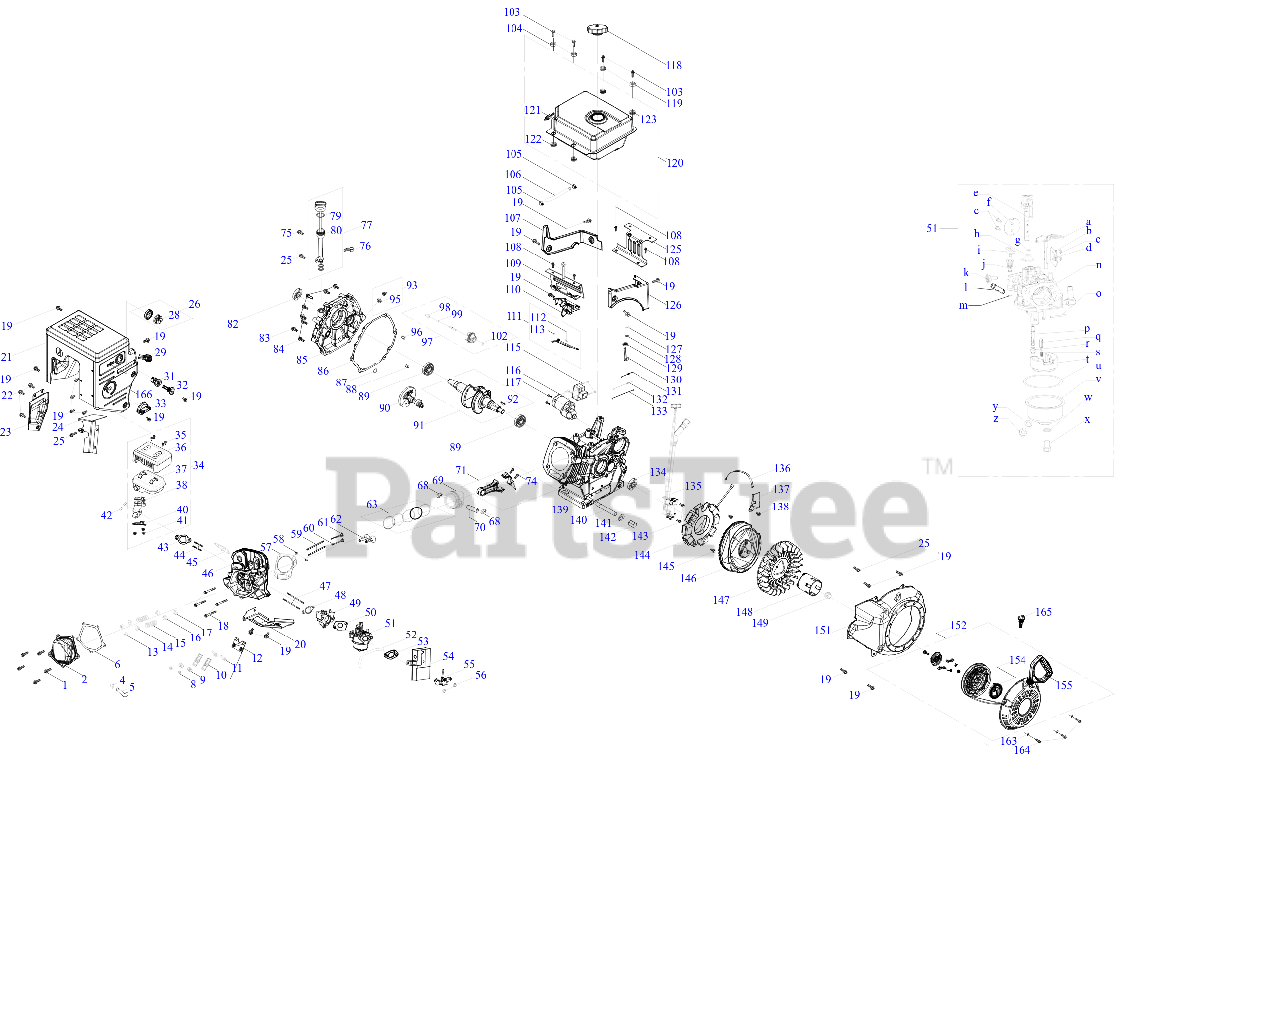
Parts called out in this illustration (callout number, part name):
1	BOLT M6-1 x 16 GR8.8
2	VALVE COVER
4	BREATHER HOSE CLAMP
5	BREATHER HOSE
6	VALVE COVER GASKET
8	PIVOT LOCKING NUT
9	VALVE ADJUST NUT
10	ROCKER ARM
11	ROCKER STUD BOLT
12	PUSH ROD GUIDE
13	EXHAUST VALVE ADJUSTER
14	EX VALVE SPRING RETAINER
15	VALVE SPRING
16	VALVE SPRING RETAINER
17	INTAKE VALVE SEAL
18	SCREW M4 x 55
19	BOLT M6-1 x 12 GR8.8
20	CYLINDER BAFFLE
21	MUFFLER SHIELD
22	BOLT M6-1 x 10 GR8.8
23	MUFFLER BAFFLE
24	CARBURETOR HEAT SHIELD
25	BOLT M6 x 16
28	PRIMER BULB
29	THROTTLE CONTROL KNOB
31	IGNITION SWITCH
32	IGNITION KEY
33	CHOKE KNOB
34	MUFFLER ASSEMBLY W/MNFLD
36	MUFFLER GUARD
37	MUFFLER BODY
38	EXHAUST MANIFOLD GASKET
40	NUT-RET EXHAUST BGBLK
41	HEX NUT M8 - 1.25
42	NUT M8-1.25
43	MUFFLER GASKET
44	STUDS M8-1.25 x 48.5
45	SPARK PLUG
46	CYLINDER HEAD
47	STUD M6-1 x 104
48	INTAKE GASKET
49	CARBURETOR INSULATOR
50	CARBURETOR GASKET
51	CARBURETOR ASSEMBLY
52	HOSE 3.2 x 6.5 x 240
53	AIR CLEANER GASKET
54	HEATE BOX
55	CHOKE ASSEMBLY
56	HEX NUT
57	CYLINDER HEAD GASKET
58	DOWEL PIN
59	PUSH ROD
60	INTAKE VALVE
61	EXHAUST VALVE
62	TAPPET
63	PISTON RING SET
68	PISTON PIN SNAP RING
69	PISTON
70	PISTON PIN
71	CONNECTING ROD ASSEMBLY
74	BOLT M8-1.25 x 38 GR10.9
75	BOLT M6-1 x 8 GR8.8
76	OIL TUBE SUPPORT BRACKET
77	DIPSTICK ASSEMBLY
79	DIPSTICK O-RING
80	OIL FILL TUBE
82	OIL SEAL
83	BOLT-M8-1.25 x 45 GR8.8
84	FLANGE BOLT M8-1.25 x 38 GR8.8
85	CRANKCASE COVER
86	CRANKCASE COVER GASKET
87	WASHER
88	DOWEL PIN
89	BEARING
90	CAMSHAFT ASSEMBLY
91	CRANKSHAFT ASSEMBLY
92	FLYWHEEL KEY
93	OIL PLUG
95	O-RING 15.8 x 2.5
96	DOWEL PIN
97	GOVERNOR ARM SHAFT
98	GOVERNOR SLIDE CAP
99	GOVERNOR SHAFT STOP RING
102	GOVERNOR GEAR WASHER
103	FLANGE BOLT M8-1.25 x 20 GR8.8
104	BUSHING
105	HOSE CLAMP
106	HOSE 3.2 x 6.5 x 240
107	FUEL TANK SHROUD
108	BOLT M8-1.25 x 14 GR8.8
109	FUEL TANK MOUNTING BRACKET
110	THROTTLE CONTROL ASSEMBLY
111	GOVERNOR ARM ASSEMBLY
112	BOLT M6-1 x 21
113	HEX NUT
115	SCREW M4 x 55
116	ELECTRIC STARTER
117	BOLT M8-1.25 x 55 GR8.8
118	FUEL CAP RED
119	BUSHING
120	FUEL TANK
121	FUEL TANK NIPPLE
122	FLAT WASHER
123	FLAT WASHER
125	FUEL TANK MOUNTING BRACKET
126	ENGINE COVER
127	GOVERNOR SHAFT CLIP
128	FLAT WASHER
129	GOVERNOR SEAL
130	GOVERNOR GEAR SHAFT
131	GOVERNOR SPRING
132	THROTTLE RETURN SPRING
133	GOVERNOR ROD
134	OIL SEAL
135	IGNITION COIL ASSEMBLY
137	ALTERNATOR WIRE CLAMP BRACKET
138	BOLT M6-1 x 8 GR8.8
139	CRANKCASE COMPLETE
140	OIL DRAIN PIPE
141	WASHER
142	OIL DRAIN PLUG
143	IGNITION COIL BOLT M6-1 x 28 GR8.8
144	ALTERNATOR
145	BOLT-M6-1 x 30 GR8.8
146	FLYWHEEL
147	COOLING FAN
148	STARTER CUP
149	NUT M16-1.5
151	BLOWER HOUSING
152	RECOIL STARTER ASSEMBLY
154	ENGINE RECOIL SPRING
155	STARTER HANDLE
163	RECOIL FLAT WASHER
164	BOLT M6-1 x 10 GR8.8
165	IGNITION KEY
166	CONTROL PANEL
